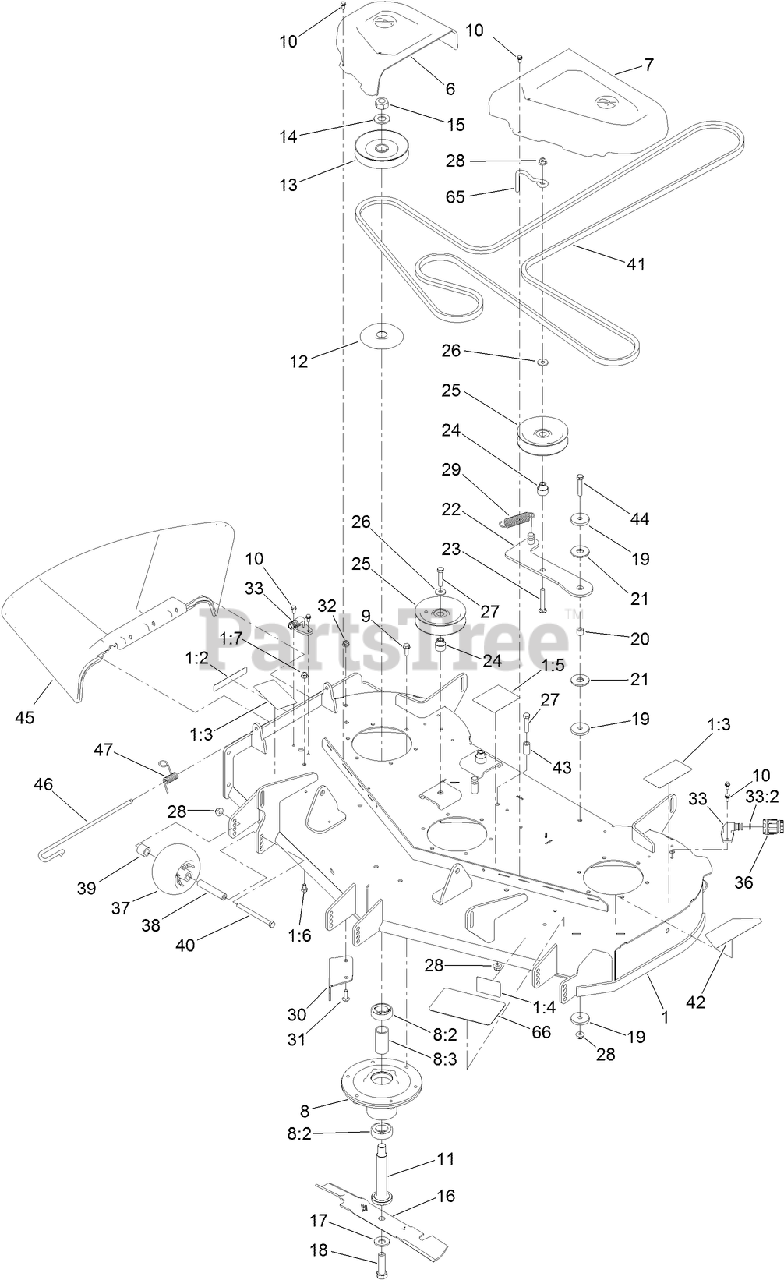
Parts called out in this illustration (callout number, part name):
1	DECK ASM
1:2	DECAL-DANGER
1:3	DECAL-DANGER, DECK
1:4	DECAL-SCALP, ANTI
1:5	DECAL-ROUTING, BELT
1:6	SCREW-HH
1:7	NUT-HF, NI
6	COVER-BELT, RH
7	COVER-BELT, LH
8	SPINDLE ASM
8:2	BEARING-BALL
8:3	SPACER-BEARING
9	SCREW-TAPTITE
10	SCREW-HWH
11	SHAFT-SPINDLE
12	SHIELD-BEARING
13	PULLEY
14	WASHER
15	NUT-HEX
16	BLADE-HI FLO, 16.50 INCH
17	WASHER-BELLEVILLE
18	SCREW-BLADE
19	WASHER-PLAIN
20	BUSHING-LEVER, LIFT
21	WASHER-FRICTION, COMPOSITE
22	ARM-IDLER
23	SCREW-CARR
24	BUSHING-IDLER
25	PULLEY-IDLER, FLAT
26	WASHER-HARDENED
27	SCREW-HH
28	NUT-HF, NI
29	SPRING-EXTENSION
30	BAFFLE-CUTOFF
31	SCREW-CARR
32	NUT-HF, NI
33	FITTING-WASHOUT
33:2	O-RING
36	CONNECTOR-HOSE
37	ROLLER-SCALP, ANTI
38	TUBE-SPANNER
39	SPACER-AXLE, REAR
40	SCREW-HH
41	V-BELT
42	DECAL-DECK
43	SPACER
44	SCREW-HH
45	DEFLECTOR-DISCHARGE
46	PIN-CHUTE
47	SPRING-TORSION
65	GUIDE-BELT, IDLER
66	TREAD-STEP
